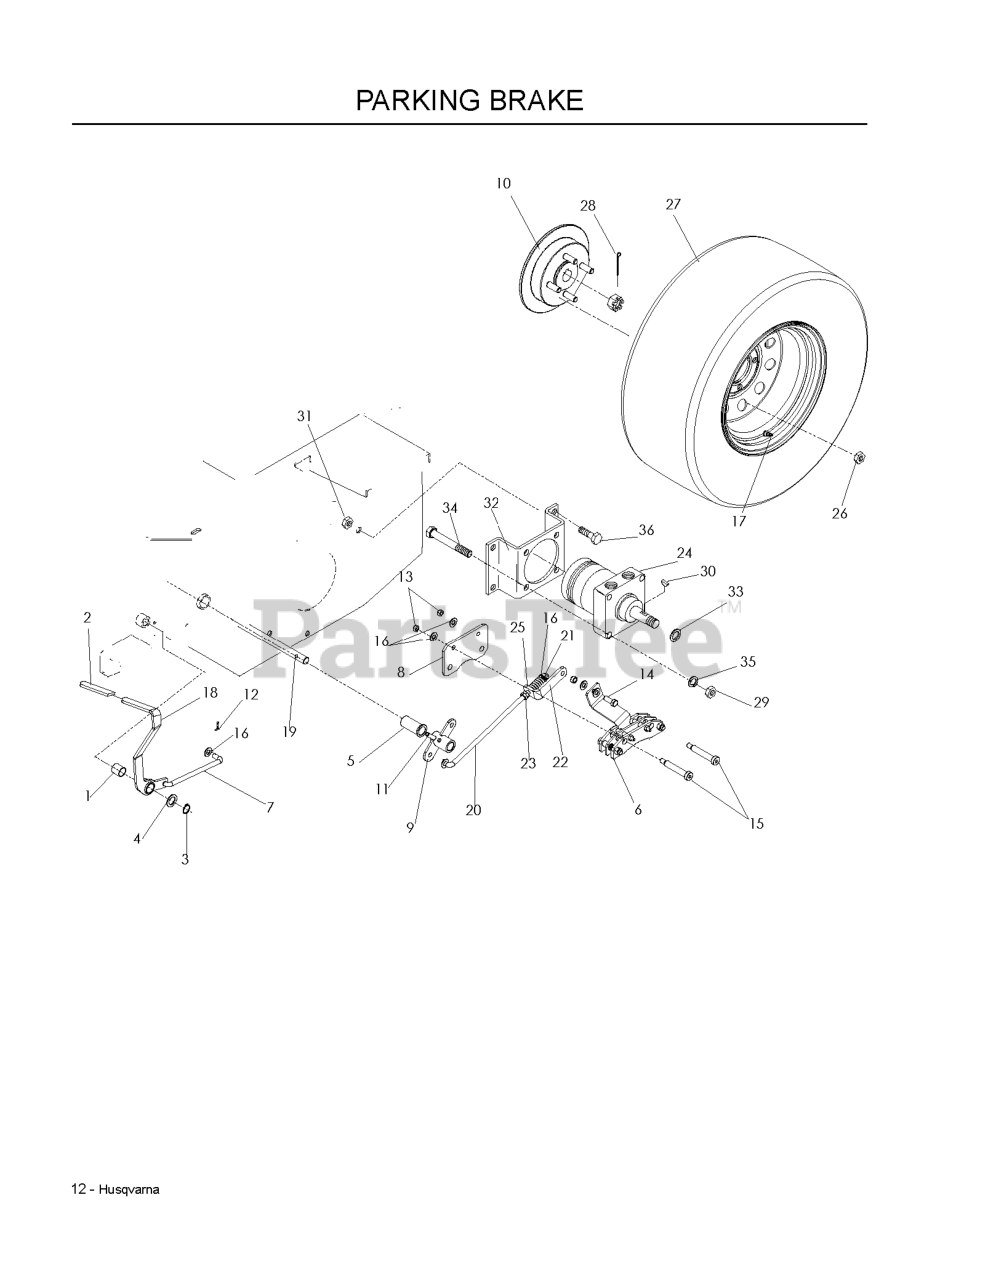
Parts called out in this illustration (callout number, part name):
2	GRIP, PARK BRAKE
3	RETAINING RING, 7/8"
4	BSHG .875 X 1.375 X .074 ZD
5	BUSHING, POLYMER 3/4X2
7	LINKAGE, BRAKE
8	PLATE, BRAKE
9	BELLCRANK, BRAKE
11	5/16 DIA ROLL PIN
12	COTTER PIN 3/32 X 3/4
13	NUT HEX 3/8-16 NYLON, THIN
14	HCS 3/8-16X1.GRD.5.ZD
15	SB 3/8-16 X 2-1-1/2 SKT HDD ZD
16	WASHER 3/8 SAE FLAT
17	VALVE STEM TR-412
18	BRAKE LEVER WLDMT
20	LINKAGE, REAR BRAKE
21	NUT 3/8F CENTERLOCK
22	BRACKET, L
23	NUT 3/8-24 JAM
24	WHEEL MOTOR, TJ
26	LUG NUT 1/2F
27	12"RIM 2.5" NEG OFFSET 8.5" W
27	ASSEMBLY, TIRE 24-12 X 12
27	TIRE.TURF.MASTER.23X9.5-12
28	PIN COTTER 4MM X 45MM
29	NUT HEX 1/2
30	WOODRUFF KEY
31	NUT 1/2-13 HEX NYLOC ZD
32	MOUNT, MOTOR, WHEEL - BLK
33	MACHINE BUSHING
34	HCS 1/2C X 2 3/4
35	WASHER 1/2" SPLIT LOCK
